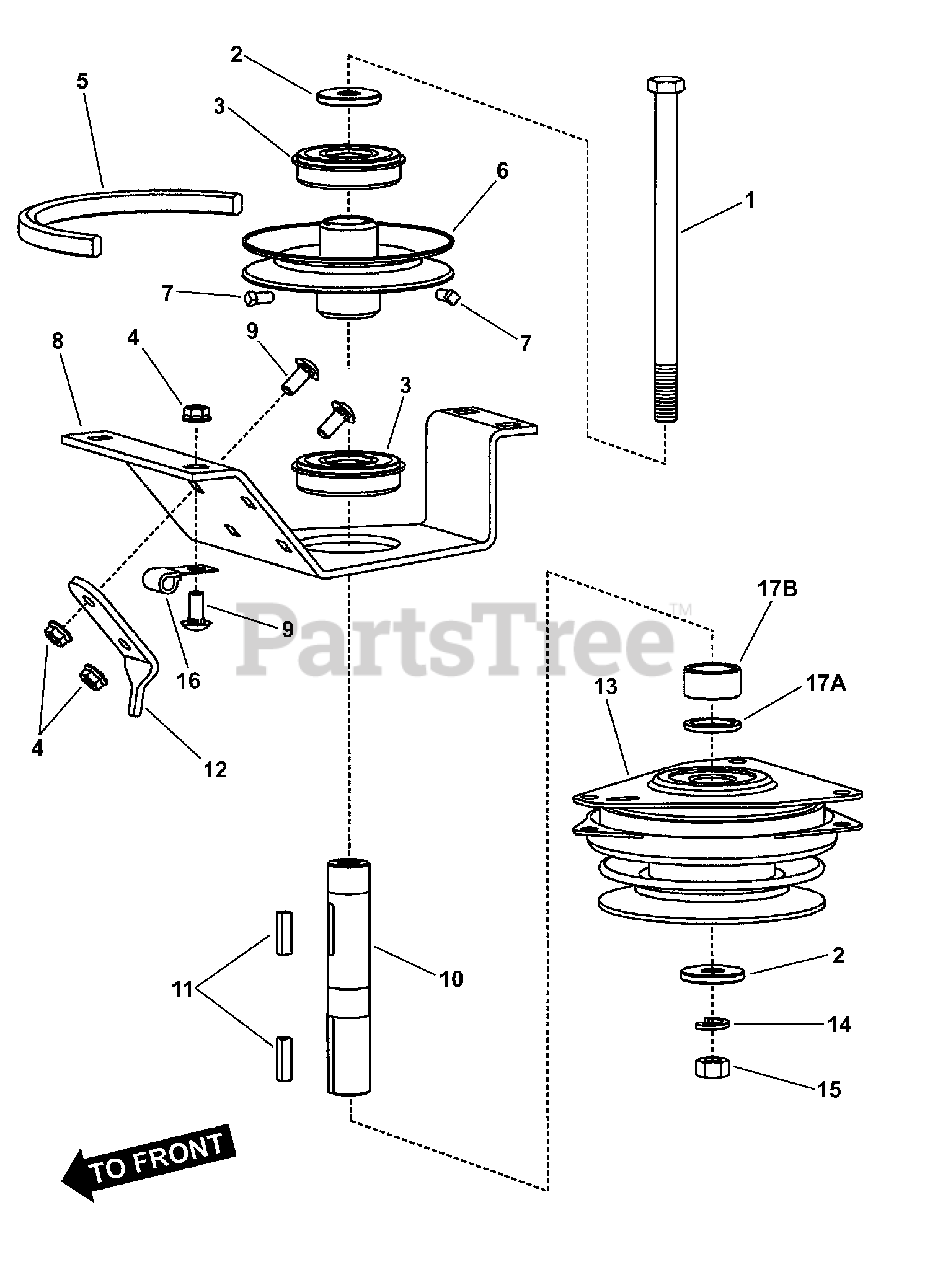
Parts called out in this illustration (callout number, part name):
1	BOLT, 7/16-20 x 8" Hex Head, GR 5
2	WASHER, .468 I.D. x 1.50 O.D. x .188 Flat
3	BEARING, 6305 w/Snap Ring
4	NUT, 5/16-18 Hex Flange Lock, GR5
5	V-BELT, 5L Sect. Cog, 50.170" effective length
6	PULLEY, Jackshaft
7	SCREW, 1/4-20 x 1/2" Set w/Patch
8	SUPPORT, Jackshaft- TG 2000
9	BOLT, 5/16-18 x 3/4" Short Neck Carriage, GR 5
10	JACKSHAFT, 5.525" long
11	KEY 1/4" Square x 1"
12	BRACKET, Anti-Rotation- TG-2000
13	CLUTCH, Warner TG-2000 (12V)
14	WASHER, 7/16" Split Lock
15	NUT, 7/16-20 Hex, GR 5 or B
16	WIRE CLIP 7/16", Vinyl Covered
17A	SPACER, Jackshaft
17B	SPACER, Jackshaft, Warner Clutch
